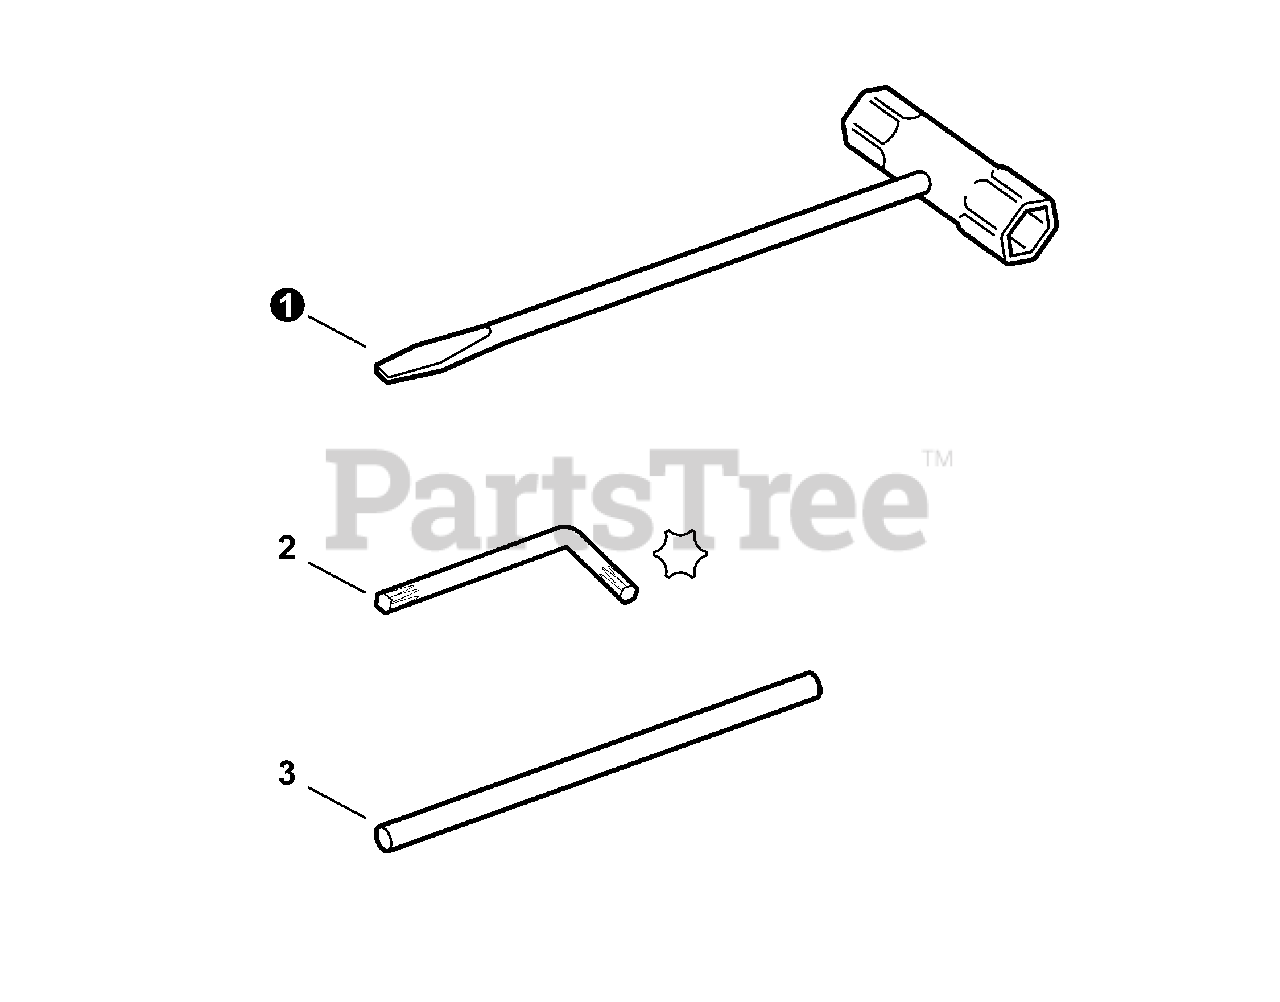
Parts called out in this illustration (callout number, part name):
1	T-WRENCH - 17×19mm
2	KEY - TORX -- T27
3	ROD, LOCKING - 5×120mm
